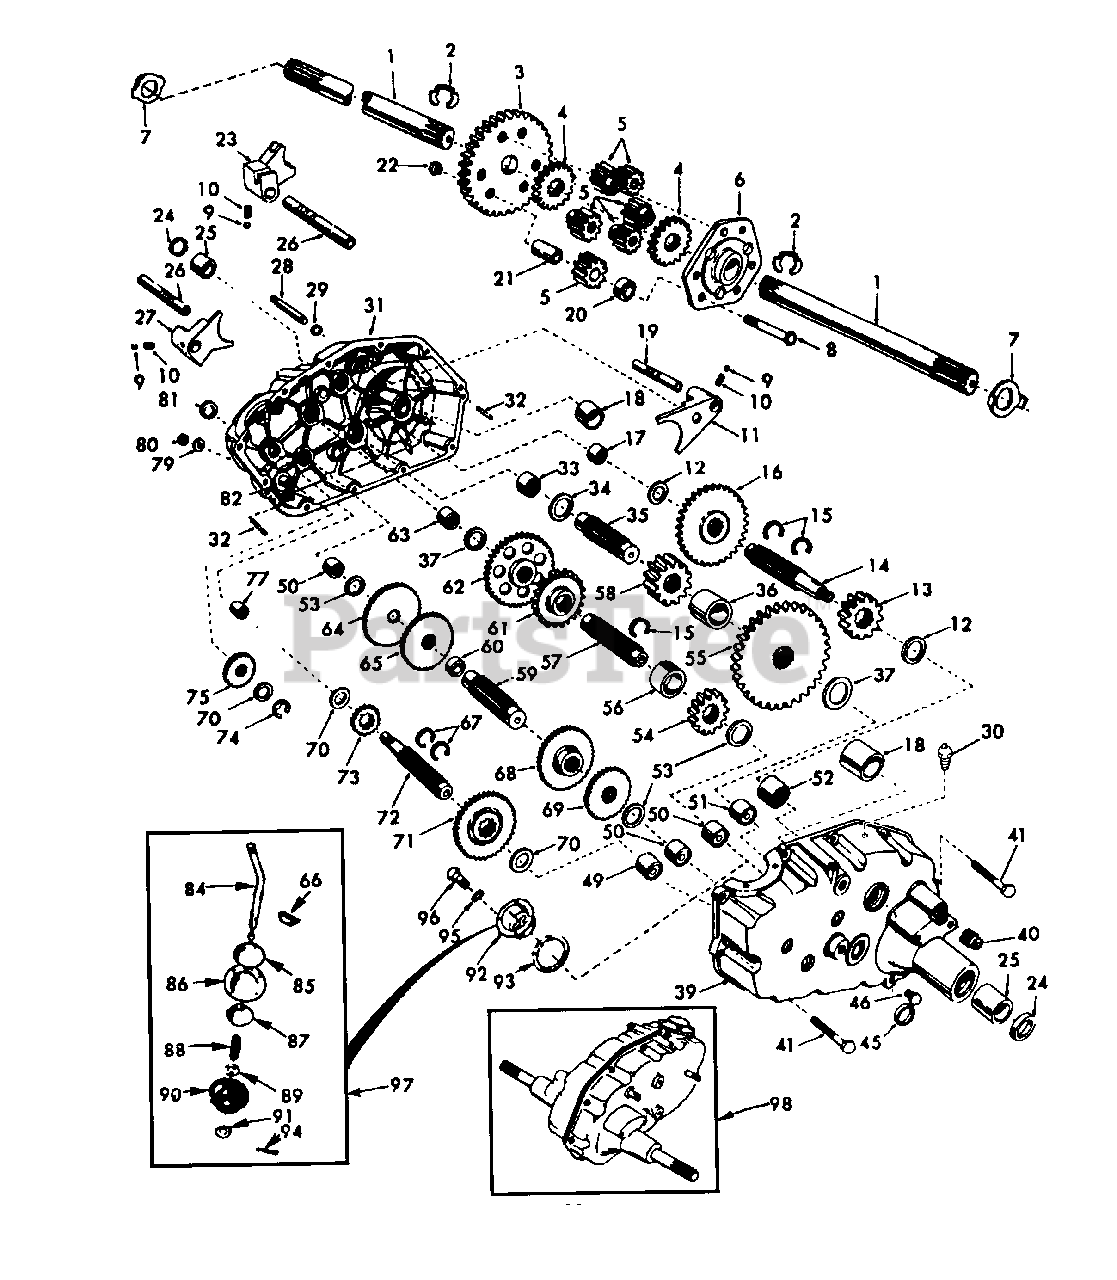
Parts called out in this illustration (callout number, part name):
1	Axle Shaft
2	Retaining Ring
3	Final Drive Gear
4	Differential Gear
5	Differential Pinion
6	Differential Carrier
7	Axle Thrust Washer
8	Bolt, Hex Head 3/8-24 x 3-1/4 (1" Thread Length)
9	Steel Ball
10	Spring Shift Fork Detent
11	Shift Fork, High-Low Range
12	Thrust Bearing Race
13	4th Reduction Pinion
14	3rd Reduction Gear Shaft
15	Snap Ring, Crescent Type
16	High-Low Range Gears
17	Needle Bearing
18	Sintered Iron Bearing
19	Shift Fork Shaft, High-Low Range
20	Differential Pinion Spacer
21	Differential Pinion Bushing
22	Gripco Centerlock Nut 3/8-24
23	Shift Fork, R.H.
24	Oil Seal
25	Sintered Iron Bearing
26	Shift Fork Shaft
27	Shift Fork, L.H.
28	Shift Shaft, High-Low Range
30	Pressure Relief Valve
31	Gearcase, Reverse Idler Shaft and Bearings, R.H.
33	Needle Bearing
34	Thrust Bearing Race
35	4th Reduction Gear Shaft
36	4th Reduction Gear Spacer
37	Thrust Bearing Race
39	Gearcase and Bearings, L.H.
40	Pipe Plug 1/2-14 N.P.T.
41	Bolt, Hex 5/16-18 UNC x 1-1/4
46	Pipe Plug 1/4-18 N.P.T.
49	Needle Bearing
50	Needle Bearing
51	Needle Bearing
52	Needle Bearing
53	Thrust Bearing Race
54	3rd Reduction Pinion, Low
55	4th Reduction Gear
56	3rd Reduction Pinion Spacer
57	2nd Reduction Gear Shaft
58	Final Drive Pinion
59	1st Reduction Gear Shaft
60	1st Reduction Shaft Spacer
61	3rd Reduction Pinion High
62	2nd Reduction Gear
63	Needle Bearing
64	Low Speed Gear and 2nd Reduction Pinion Cluster
65	Reverse Gear
66	Key, Hi-Pro 1/8 x 17/32
67	Snap Ring, Crescent Type
68	Intermediate Speed Gear
69	High Speed Gear
70	Thrust Bearing Race
71	intermediate and High Speed Cluster Pinions
72	Input Shaft
73	Low Speed Pinion
75	Reverse Idler Gear
77	Needle Bearing
79	Sealing Washer
80	Nut, Hex, Jam 7/16-20
81	Oil Seal
82	Reverse Idler Shaft
84	Gearshift Lever, Bent
85	Gearshift Cap
86	Gearshift Ball Cover and Pin
87	Shift Lever Guide Ball, Keyed
89	Washer 15/32 x 15/16 x 16 Gauge
90	Shift Mechanism Seal
91	Washer 9/16 x 15/16 x 12 Gauge
92	Gearshift Gate and Reinforcement
93	Shift Ball Cover Gasket
94	Cotter Pin 1/8 x 3/4
95	Washer, Lock 5/16
96	Bolt, Hex Head 5/16-18 UNC x 7/8
97	Gear Shift Lever Assembly
98	Transaxle, 6 Speed, Complete Assembly
